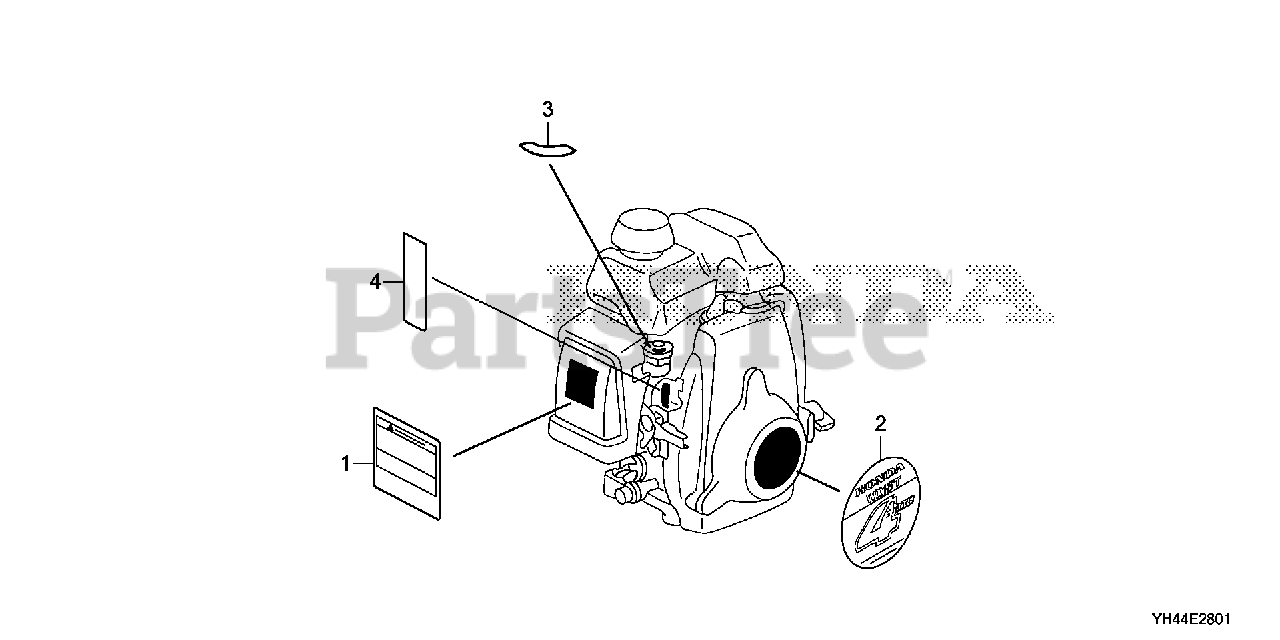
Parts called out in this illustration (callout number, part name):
1	MARK, OPERATOR CAUTION (ENGLISH)
3	MARK, PETCOCK (EXTERNAL)
4	MARK, THROTTLE INDICATION
